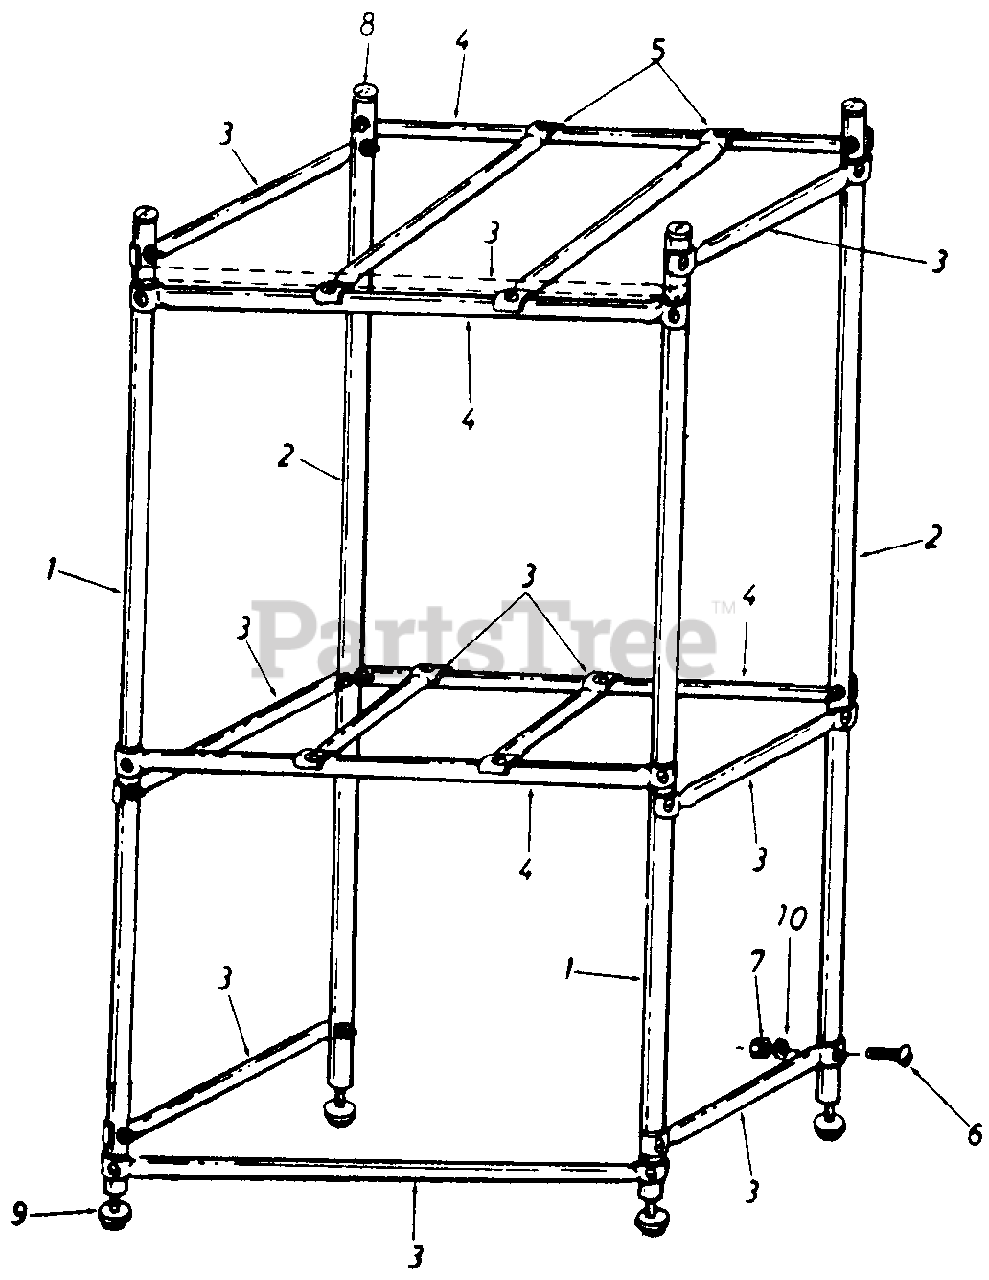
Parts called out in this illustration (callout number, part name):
3	Cross Brace w/o Center Holes 31" Lg.
6	Truss. Mach. Screw 1/4- 20 x 1-1/2" Lg.
7	Hex Nut 1/4-20 Thd.
8	1" Tubing Plug
9	1" Swivel Glide
10	Lock Washer 1/4" I.D.
